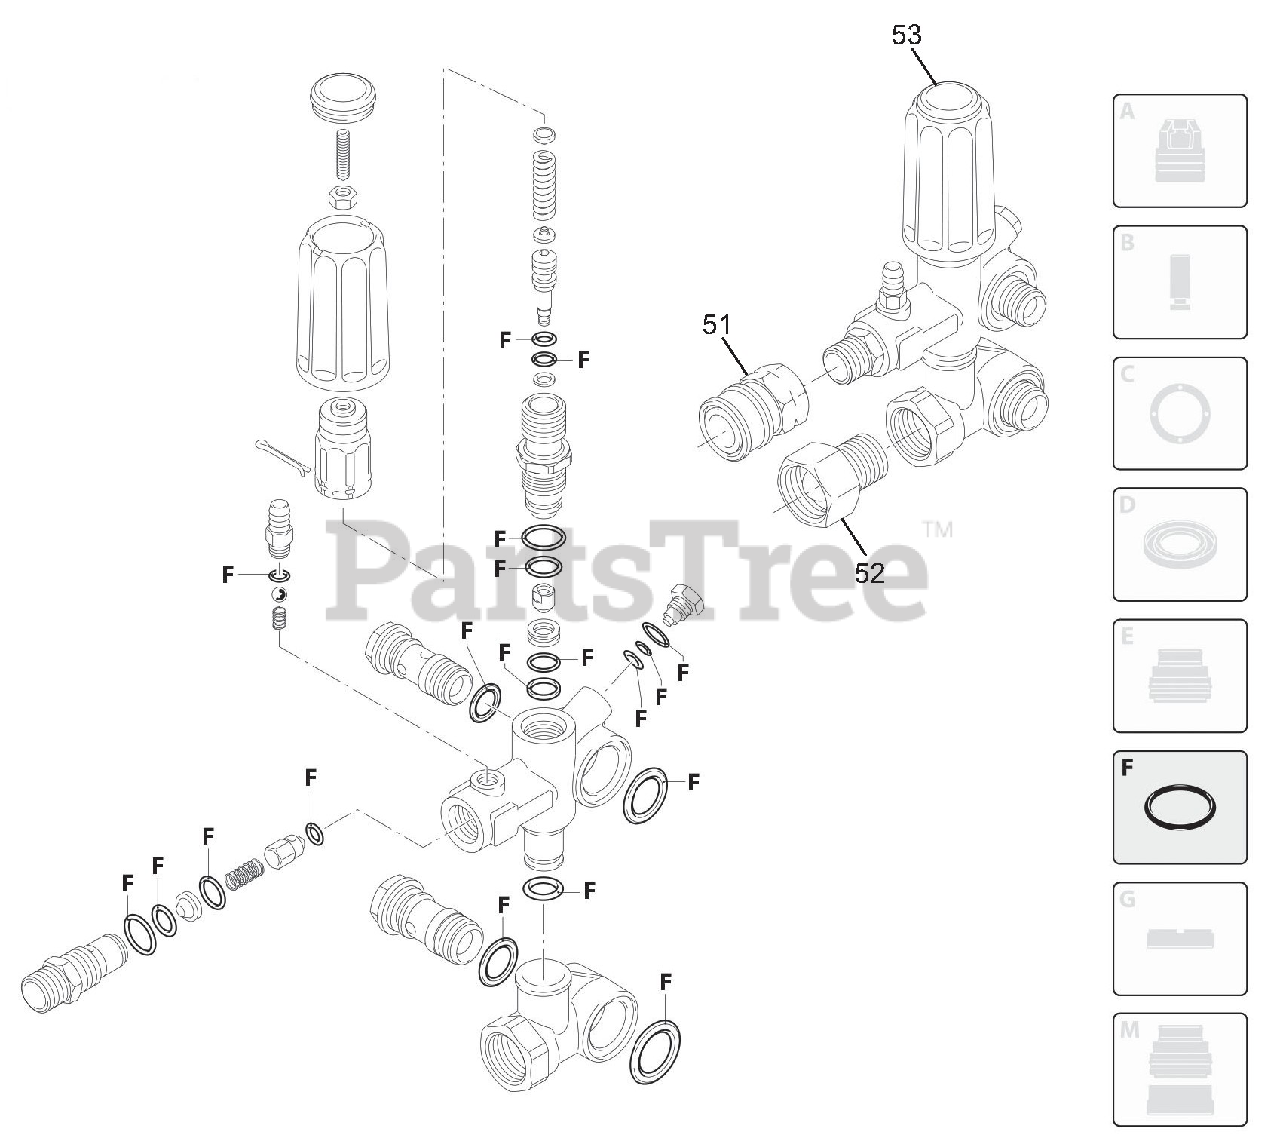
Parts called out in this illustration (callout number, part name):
51	UNLOADER FITTING
52	UNLOADER FITTING
53	UNLOADER VALVE ASSEMBLY
